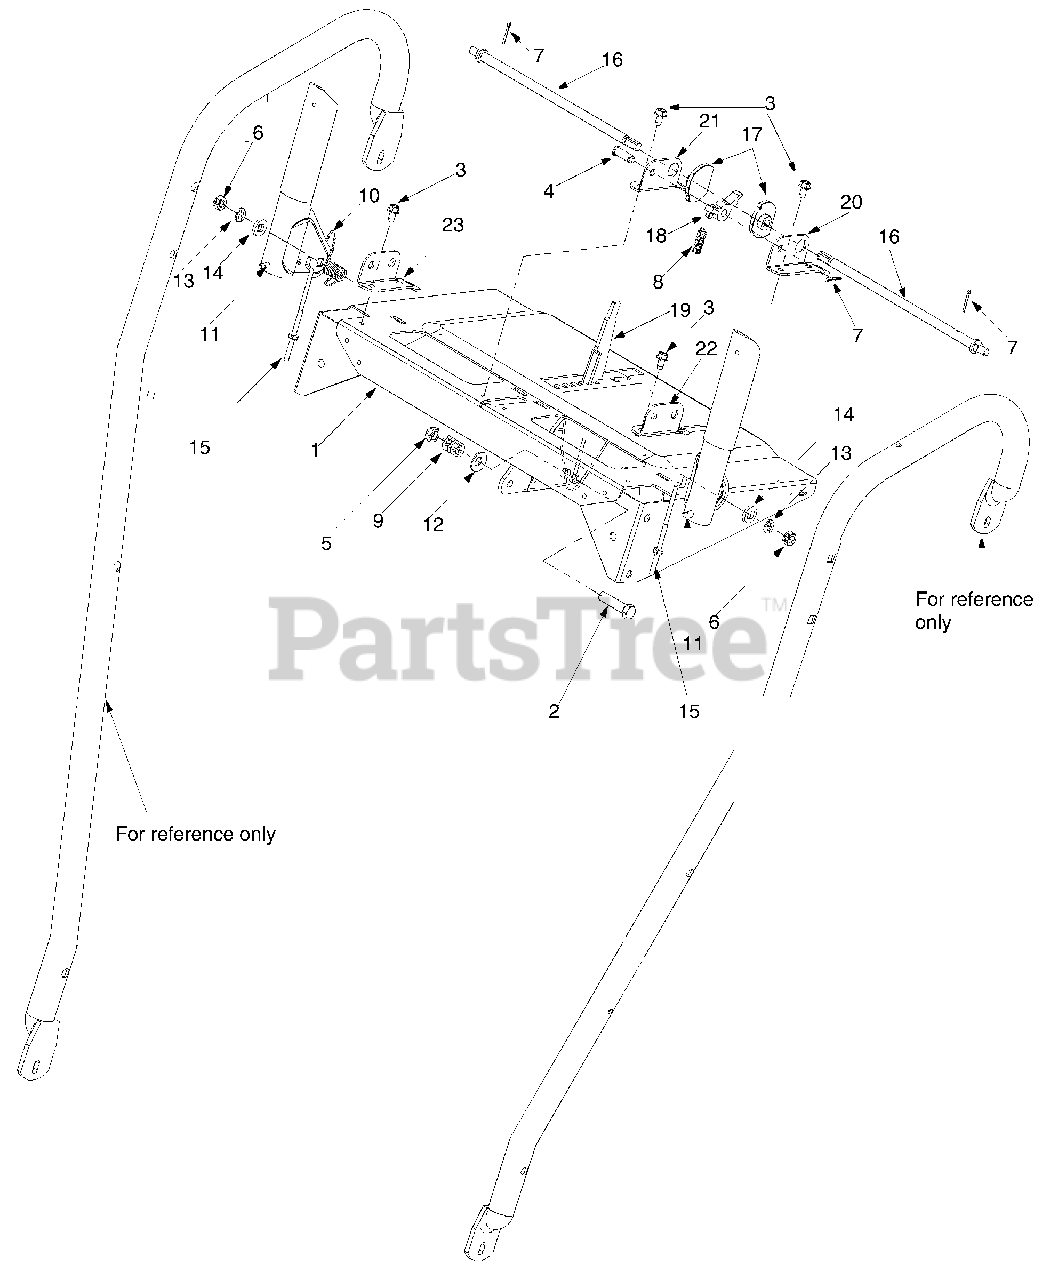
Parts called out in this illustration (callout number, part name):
2	Hex Bolt: 3/8-24 x 1.5 Gr.5
3	Hex Washer Head TT Screw: 1/4-20 x 0.5
4	Clevis Pin
7	Cotter Pin
8	Compression Spring
9	Compression Spring
10	Torsion Spring
11	Rubber Bumper
12	Bell Washer
13	Lock Washer
14	Special Washer
15	Z Fitting: Cable
17	Cam Handle Lock
18	Pawl: Handle Lock
